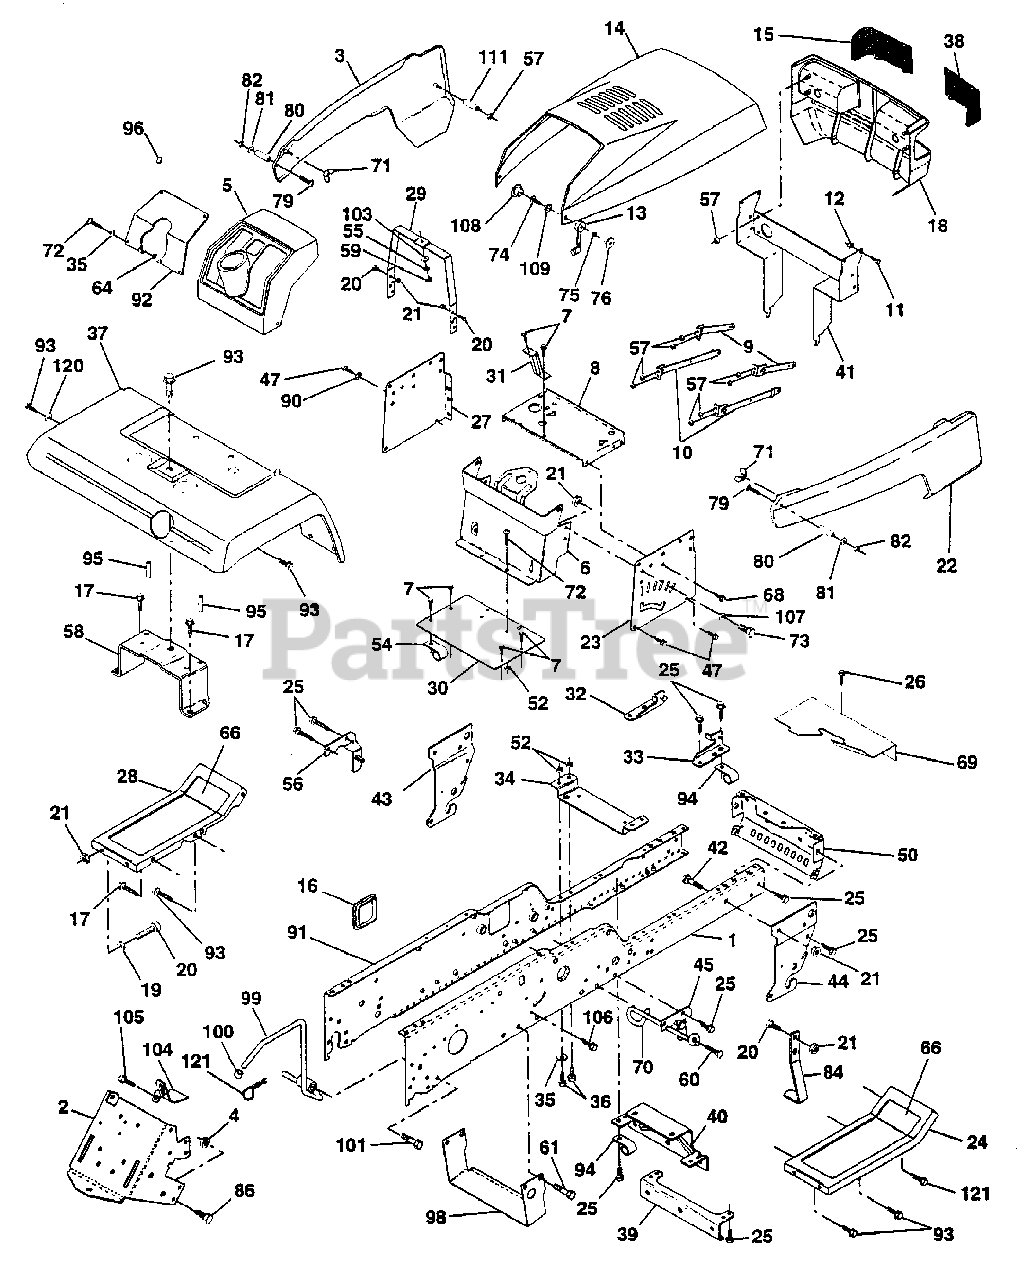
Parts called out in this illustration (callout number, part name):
1	Rail, Frame RH
2	Drawbar, Gt
3	Panel Asm., Side LH
4	Nut, Lock Hex 7/16 Unc
5	Dash, Plastic Black
6	Dash Asm., Lower
7	Screw, Thd Cut 1/4-20 x 1/2
8	Support, Battery
9	Strap, Asm. Hinge Front
10	Strap, Asm. Hinge Rear
11	Bolt Shoulder 1/4-20
12	Nut Crownlock 1/4-20
13	Latch, Chute Blk
14	Hood Asm., Pnt
15	Lens, Headlight RH
16	Cover, Access
17	Screw, Thdrol 3/8-16 x 3/4
18	Grille
19	Washer 13/32 x 13/16 x 12 Ga.
20	Bolt, Fin Hex 3/8-16 x 1
21	Nut, Lock Hex W/Wsh 3/8-16 Unc
22	Panel Asm., Side RH
23	Panel, Dash Side RH
24	Footrest, RH
25	Screw, Thdrol 3/8-16 x 3/4
26	Screw, Thdrol 5/16-18 x 3/4
27	Panel, Dash Side LH
28	Footrest, LH
29	Bracket, Support Dash
31	Brace, Support Steering
32	Bracket Asm., Frame Pivot Lh
33	Bracket Asm., Frame Pivot Rh
34	Bracket, Engine Support Rear
35	Washer 11/32 x 11/16 x 16 Ga.
36	Bolt, Fin Hex 5/16-18 x 3/4
37	Fender, Pnt.
38	Lens Headlight LH
39	Bracket, Axle Front
40	Bracket, Support Axle/Engine
41	Support Asm. Grille
42	Bolt, Carriage 3/8-16 x 1
43	Bracket, Spnsn Front Lh
44	Bracket, Spnsn Front Rh
45	Bracket Asm., Susp Chassis Rh
47	Screw Thdrol 3/8-16 x 1 /2
50	Bracket, Chassis Front
52	Locknut, Hex W/Ins 5/16-18 Unc
54	Clip, Insulated
55	Washer 9/32 x 3/4 x 16 Ga.
56	Bracket Asm., Susp Chassis Lh
57	Nut Keps Hex 1/4-20
58	Bracket Asm., Fender
59	Nut Fin Hex 1/4-20
60	Screw Thdrol 3/8-16 x 1-1/4
61	Screw Thdrol. 3/8-16 x 3/4
62	Retainer Spring
64	Nut 5/16-18
66	Pad, Footrest
68	Screw, Thdrol 5/16-18 x 1/2
69	Shield, Heat
70	Guide, Belt Mid Span
71	Nut, Plastic Locking Wing 1/4-20
72	Screw, Mach Trhd 5/16-18 x 3/4
73	Bolt, Fin Hex 3/8-16 x 1 Gr. 5
74	Screw, Machine #10-24
75	Washer, Lock #10
76	Nut, Weld #10-24
79	Screw, Machine #10-24 x 1/4
80	Spacer, Split
81	Washer 7/32 x 1/2 x 18 Ga.
82	Nut #10-24
84	Stop, Over Center Mower
86	Bolt, Fin Hex 7/16-14 Unc x 1
90	Washer, Lock External Tooth 3/8
91	Rail, Frame Lh
92	Plate, Silkscreen Dash
93	Screw, Thdrol 3/8-16 x 1/2
94	Clip, Fuel Line
95	Push Nut, Nylon
96	Plug, Hole
98	Bracket Chassis Skid
99	Rod Asm.Bypass
100	Cap Brake Parking Red
101	Screw Thdrol. 3/8-16 x 1-3/4
103	Washer, Lock 1/4
104	Bracket Lock Bypass
105	Screw Thdrol. 5/16-18 x 1/2
106	Screw Thdrol. 5/16-18 x 1.25
107	Washer 13/32 x 1 x 14 Ga.
108	Cap, Snap Black
109	Cap, Washer Snap
120	Washer 13/32 x 1 x 16 Ga
121	Screw Thdrol 3/8-16 x 1 Ty-tt
